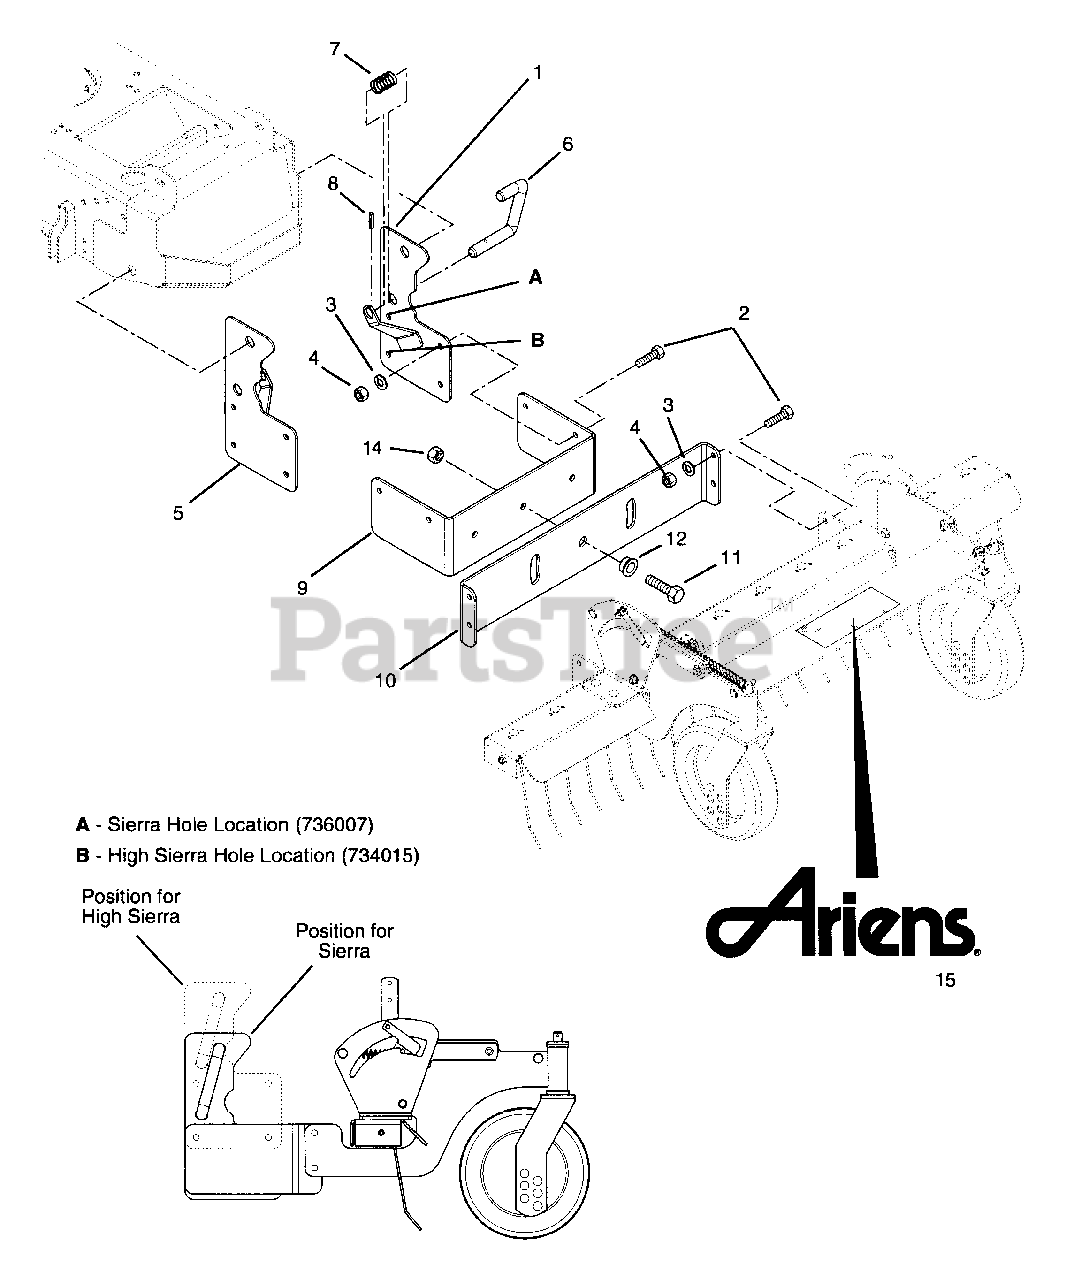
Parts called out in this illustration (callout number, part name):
1	PIVOT - FRAME LH
2	@BLT-HEX .31-18X.75 GR5 YWZC
3	WSHR-LK .312X.097 HVY YWZC
4	@NUT-HEX .31-18 YWZC
5	PIVOT - FRAME RH
6	PIN, LATCH
7	SG-COMP .072X.77X1.75
8	PIN-ROLL .188X1.00
9	STABILIZER - PIVOT FRAME
10	STABILIZER - CHANNEL SUPPORT
11	@BLT-HEX .38-16X1.00 GR5 YWZC
12	BSHG-FLG .390X.625X.328X.875
13	@WSHR-LK .38X.094 REG YWZC
14	@NUT-HEX .38-16 YWZC
15	DECAL-ARIENS
